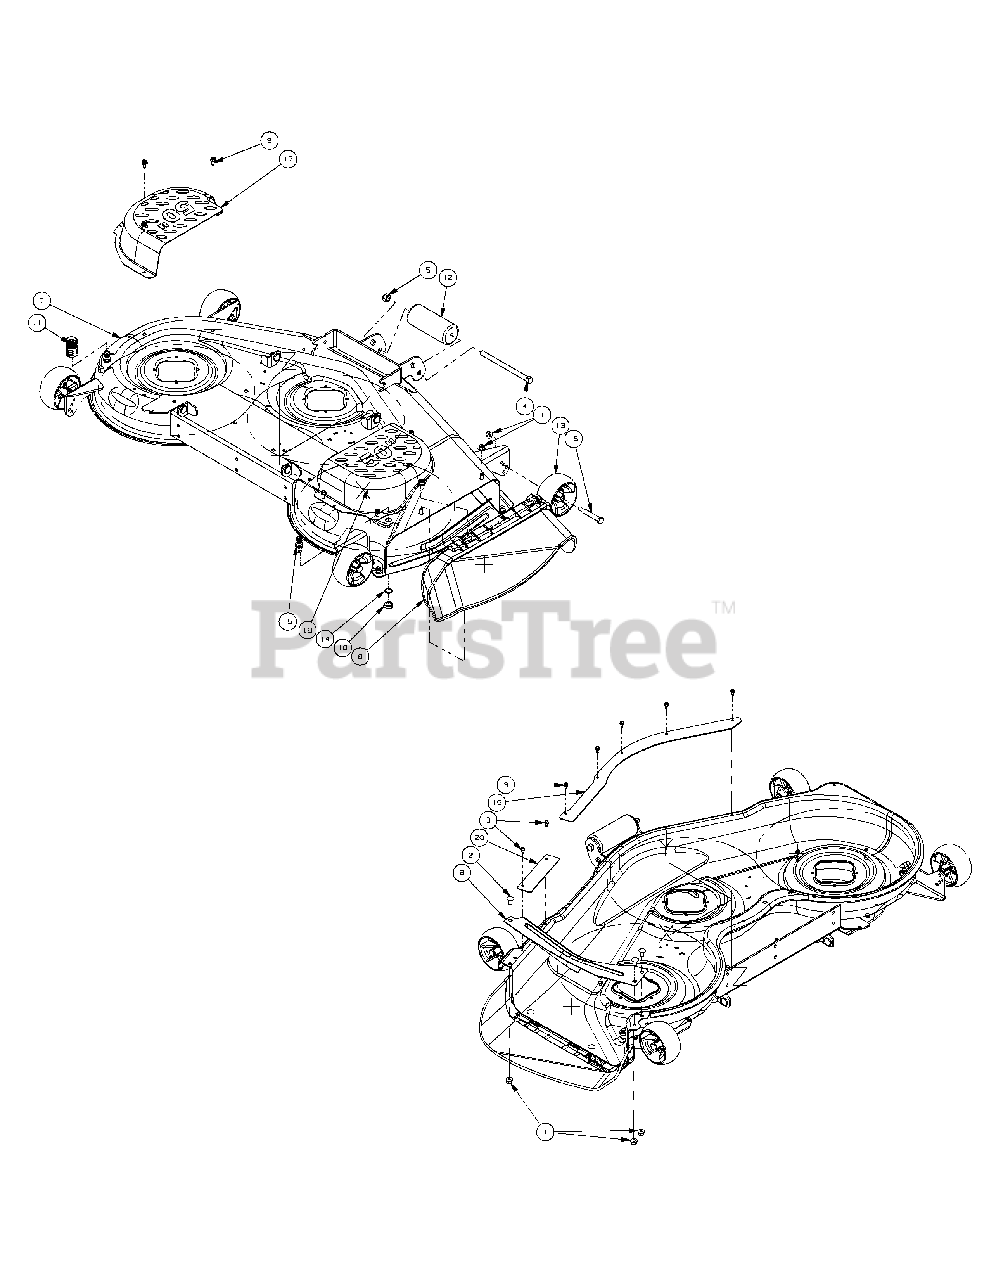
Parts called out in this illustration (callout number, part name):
1	Hex Nut, 3/8-16, Flange Lock
2	Carriage Bolt, 3/8-16 x .75
3	Screw, 1/4-20 x 1/2
4	Hex Cap Screw, 1/2-20 x 7.50
5	Nut, 1/2-20, Lock
6	Chute Assembly
9	Self Tapping Screw 5/16-18 x .750
10	Hex Nut, M16-1.5
11	Water Nozzle Adaptor
12	Front Roller
13	Deck Wheel, 5.00 Dia.
14	Lock Washer, 17 x 23.8 x 1.95
15	Deck Water Nozzle
16	Shoulder Screw .498 x 1.53
